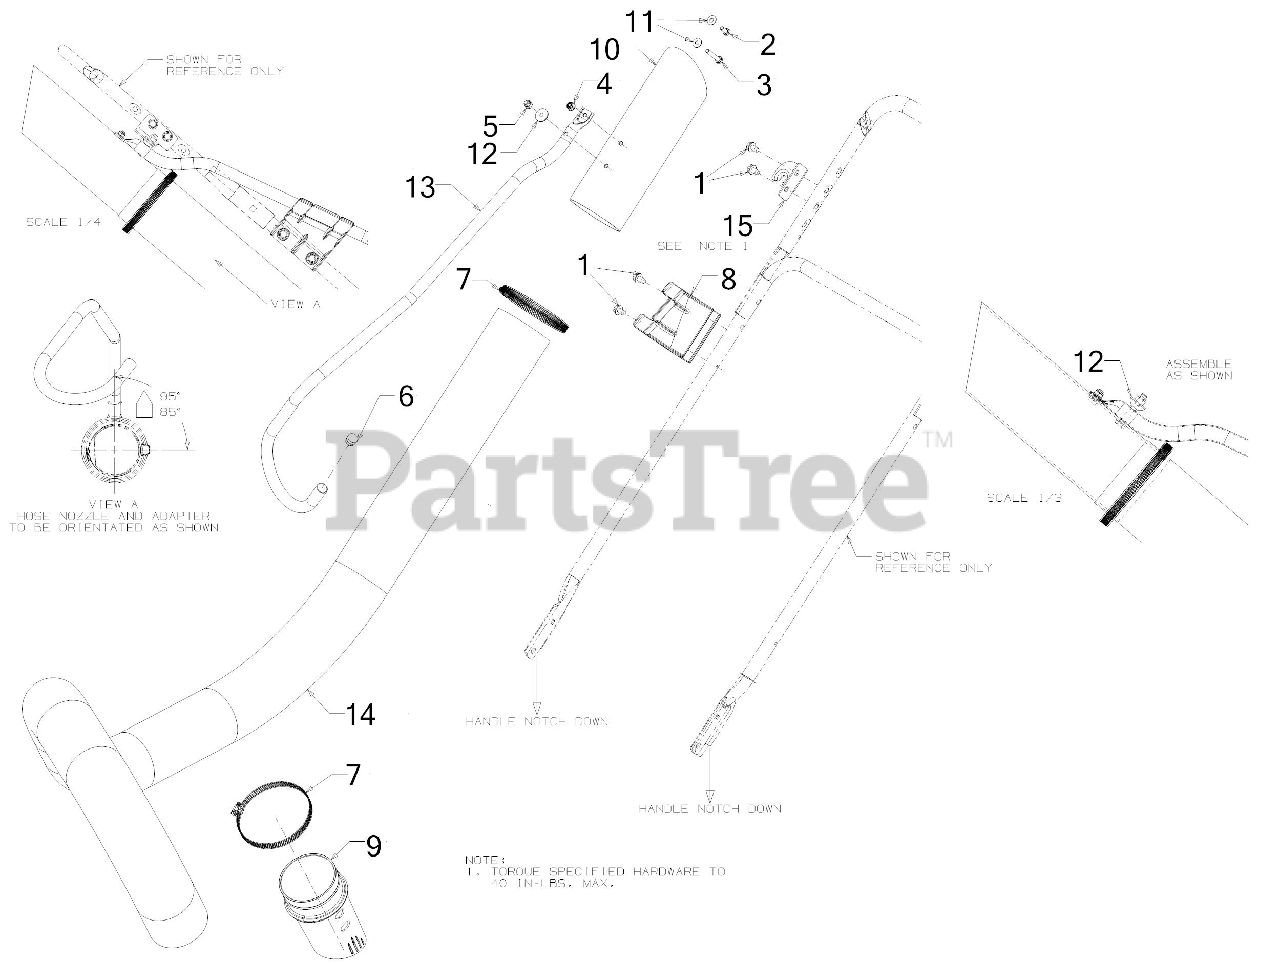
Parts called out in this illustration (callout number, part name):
1	SCREW 5/16-18 x .500
2	SCREW 1/4-20 x .620 GR5
3	BOLT 1/4-20X1.62 GR5
4	FLANGE LOCK NUT
5	HEX ACORN NUT
6	HANDLE PLUG
7	HOSE CLAMP
8	CLIP-HANDLE NOZZ
9	HOSE ADAPTER
10	HOSE NOZZLE 3.875
11	FLAT WASHER .271:.630:.065
12	HOSE HANGER SPACER
13	NOZZLE HANDLE
14	VACUUM HOSE 4.0 x 75.0
15	UPPER HANDLE BRACKET
